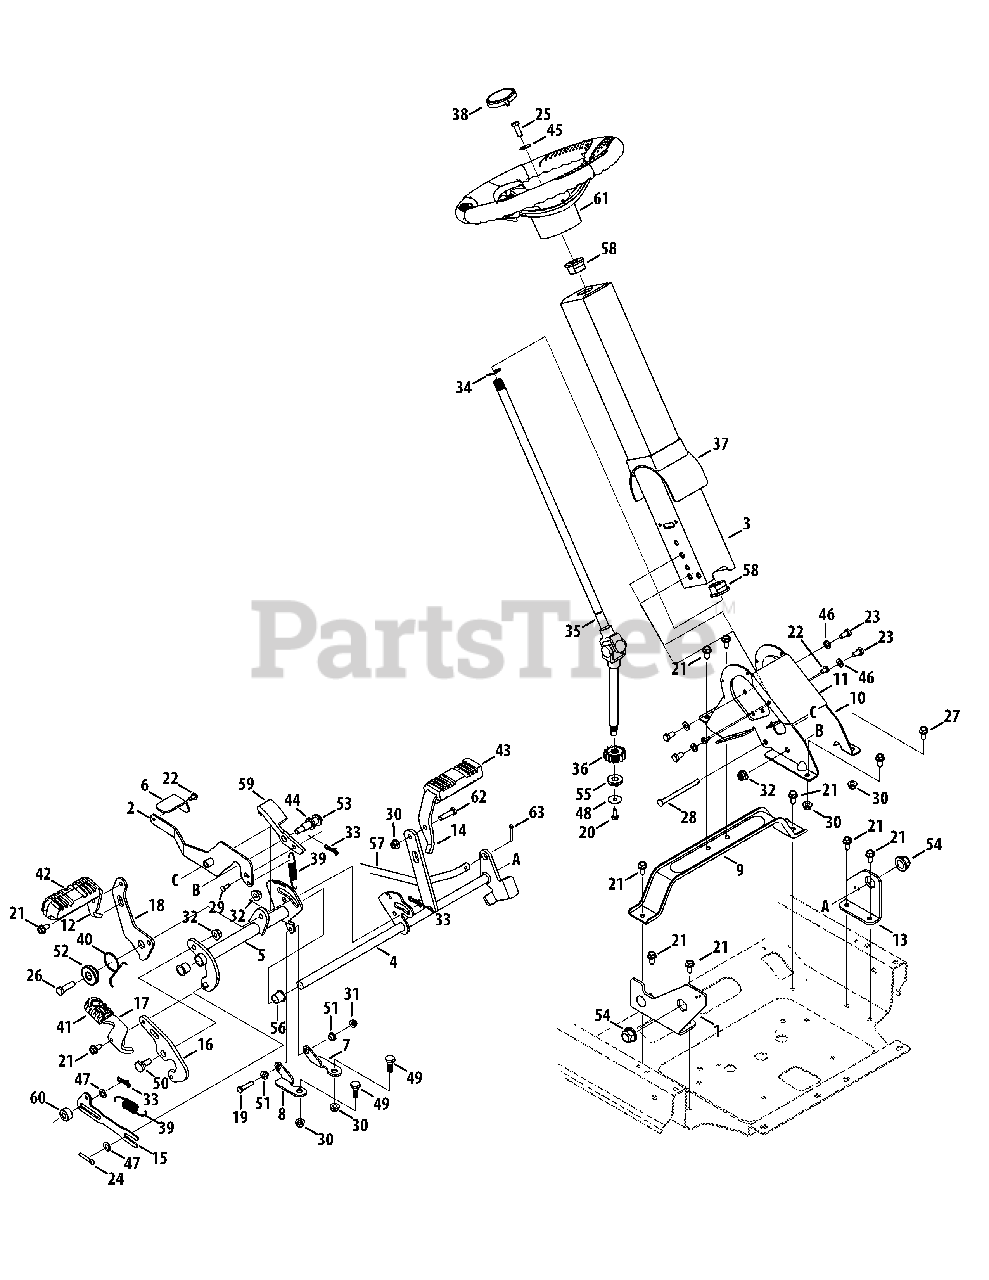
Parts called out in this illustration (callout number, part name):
1	Support Bracket Assembly, RH
2	Brake Pedal Assembly
3	Steering Column Assembly
4	Brake Pedal Assembly
5	Drive Pedal Assembly
6	Tilt Steering Pedal
7	Speed Bracket, LH
8	Speed Bracket, RH
9	Steering Support Bracket
10	Lower Steering Wheel Column
11	Lower Column Cover
12	Drive Pedal
13	Support Bracket, LH
14	Brake Pedal
15	Return to Neutral Link
16	Reverse Pedal Bracket
17	Reverse Pedal
18	Forward pedal Bracket
19	Hex Head Screw, 1/4-20 x 1.25
20	Hex Head Screw, 1/4-20 x .625
21	Hex Washer Screw, 5/16-18 x .750
22	Screw, 1/4-20 x .5
23	Hex Screw, 5/16-18 x .625
24	Cotter Pin, .125 x .75
25	Hex Screw, 5/16-24 x.875
26	Hex Screw, 3/8-16 x 1.25
27	Hex Screw, 5/16-18 x .75
28	Clevis Pin, 5/16 x 4.135
29	Clevis Pin, .224 Dia. x .625
30	Flange Lock Nut, 5/16-18
31	Flange Lock Nut, 1/4-20
32	Flange Lock Nut, 3/8-16
33	Bow-Tie Cotter Pin, 72
34	E-Ring, .750
35	Steering Shaft
36	14-Tooth Spur Gear
37	Column Cover
38	Steering Wheel Cover
39	Extension Spring, .70 OD x 3.035 LG
40	Torsion Spring, 1.00 ID x .22
41	Reverse Pedal Pad
42	Forward Pedal Pad
43	Brake Pedal Pad
44	Flat Washer, .535 x .930 x .090
45	Bell Washer, .340 x .872 x .060
46	Flat Washer, .330 x .630 x .064
47	Thrust Washer, .375 x .700 x .030
48	Flat Washer, .265 x 1.00 x .030
49	Shoulder Screw, 5/16-18 x .437 x .268
50	Shoulder Bolt, 3/8-16 x .500 x .270
51	Shoulder Spacer, .375 x .625 x .20
52	Shoulder Spacer, 1.50 x .38 x .38
53	Shoulder Screw, 3/8-16 x .496 x 1.445
54	Hex Flange Bearing
55	Hex Flange Bearing, 7/16
56	Flange Bearing, .63 ID x .695 OD x .06
57	Front Brake Rod
58	Flange Bearing, .63 ID x 1.50
59	Cruise Latch
60	Spacer, .385 ID x .875 OD x .458
61	Steering Wheel Assembly
62	Hex Cap Screw, 5/16-18 x 1.00
63	Cotter Pin, 5/32 x 1.25
